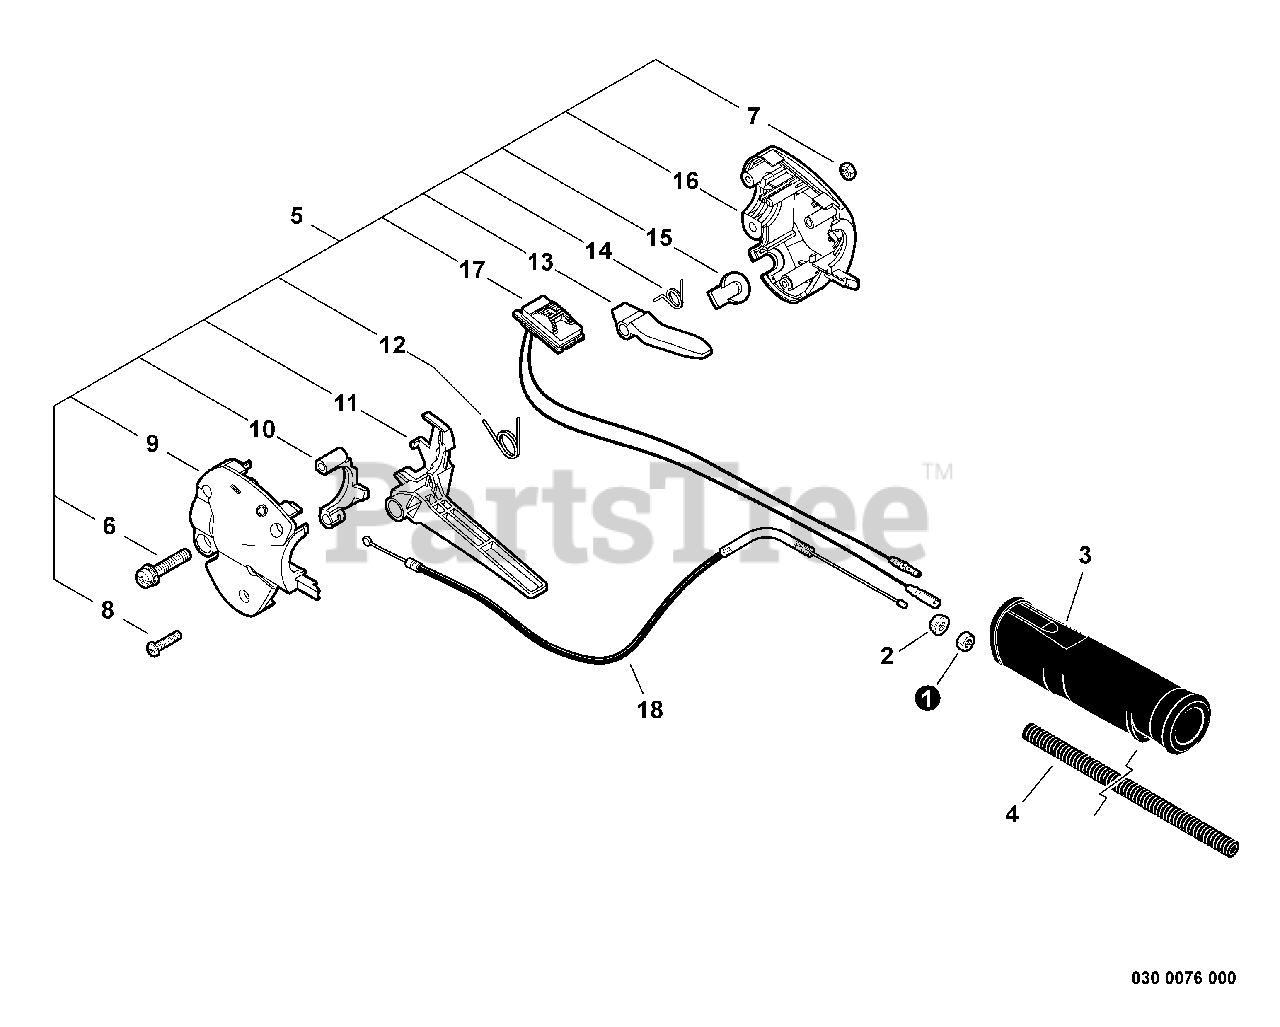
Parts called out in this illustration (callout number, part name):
2	NUT - 6 -- FLANGE
4	TUBE, PROTECTIVE - CORRUGATED
5	CONTROL HANDLE KIT
6	SCREW - 5X16
8	SCREW - 4X20 -- TAPPING
9	HANDLE, CONTROL - LEFT
10	LOCKOUT, THROTTLE
11	TRIGGER, THROTTLE
12	SPRING, TRIGGER
13	LEVER, TRIGGER LOCKOUT
14	SPRING, LOCKOUT LEVER
16	HANDLE, CONTROL - RIGHT
17	SWITCH, IGNITION
18	CABLE, THROTTLE
